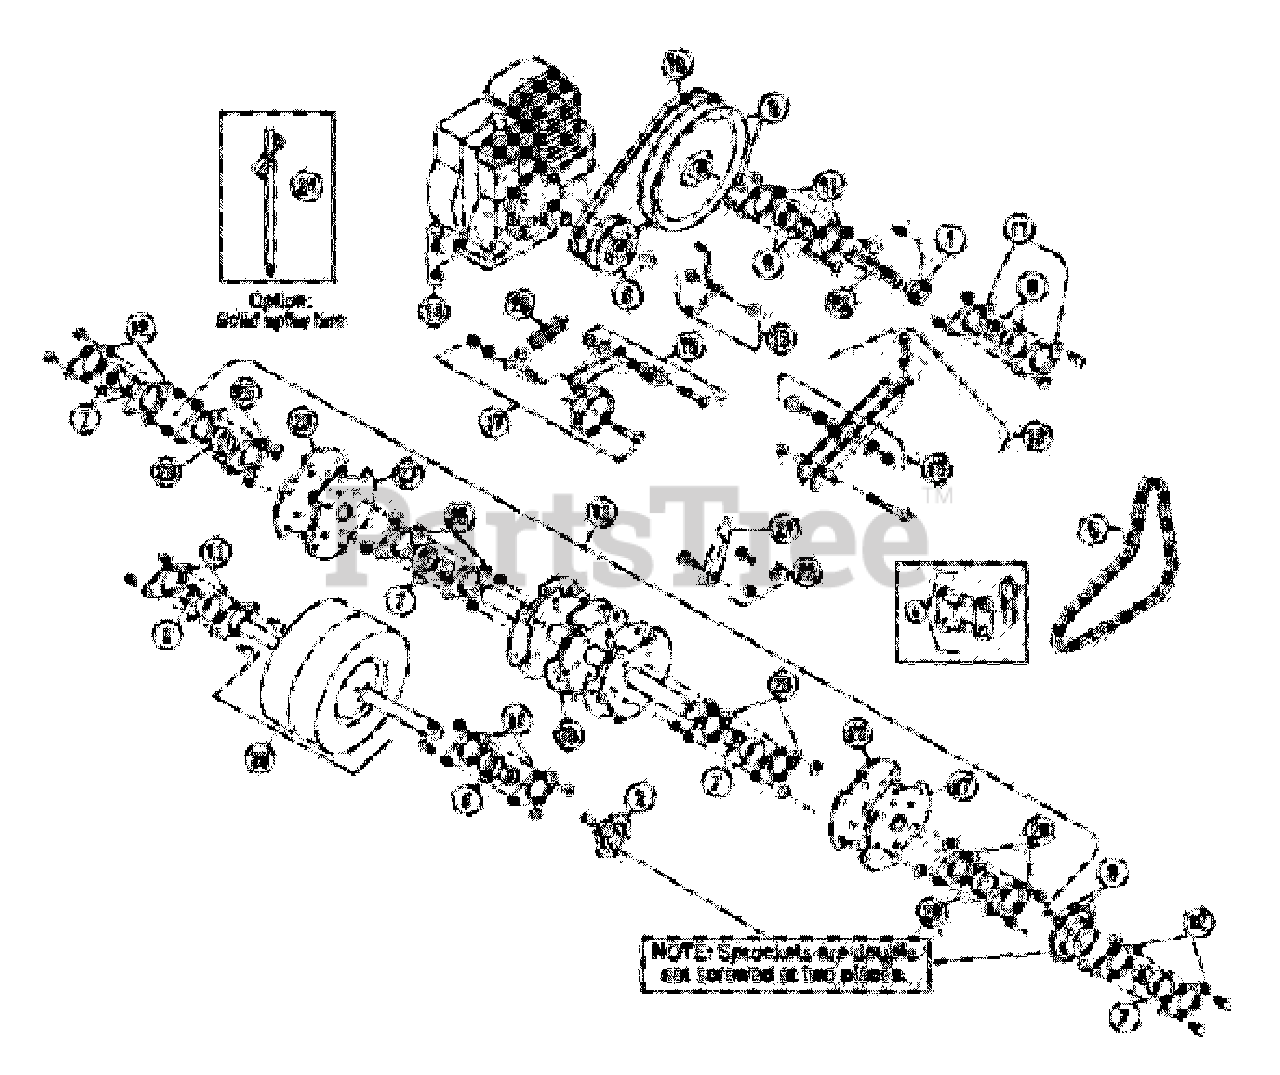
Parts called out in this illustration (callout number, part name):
1	Sprocket, jackshaft, with key and spacer
2	Sprocket, wheel, with set screws and key
3	Sprocket, rotor, with set screws and key
4	Master link
5	Chain, #40 perma lube roller
6	Bearing, 3/4" with lock collar
7	Bearing, 1" with lock collar
8	V-pulley, A-4" with set screws and key
9	V-pulley, A-10" with set screws and key
10	V-belt, A-44" special
11	Stamping kit w/fasteners
12	Stamping kit w/fasteners
13	Rotor shaft, tine without bolts
14	Fastener kit, engine
15	Belt keeper kit
16	Idler arm kit, pulley
17	Idler pulley kit
18	Idler arm kit, chain
19	Idler sprocket kit, chain
20	Front wheel and shaft kit
21	Tine set, closed spoon, 30 each
21	Tine set, closed spoon, 6 each
22	Tine/spike fastener kit, 72 ea. bolts and nuts
22	Tine/spike fastener kit, 12 ea. bolts and nuts
23	Jackshaft, with key
24	Spike set, 30 each
25	Stamping kit, w/nuts and washers
26	Bearing 1"
27	Left rotor plate
28	Right rotor plate
29	Spring clutch
30	Rotor shaft, center
